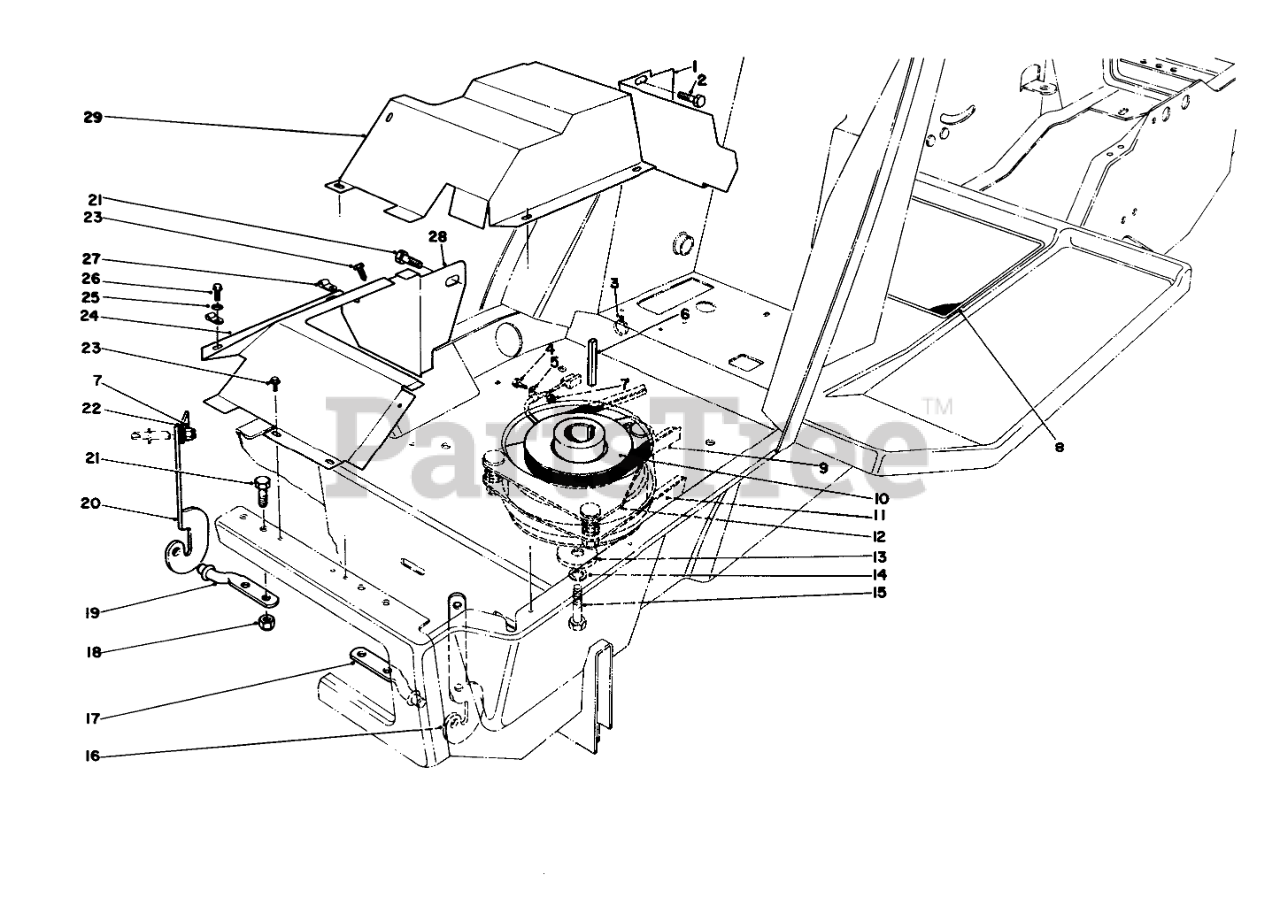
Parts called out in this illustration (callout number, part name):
1	EXH SHIELD SUPT B
2	SCREW-HH
3	TIE-MOUNT, PUSH
4	SCREW-HH
5	CLAMP
6	KEY-SQUARE
7	NUT-LOCK, NI
8	OPERATION DECAL
9	V BELT
10	Pulley
11	V-BELT
12	Clutch Assembly-Deck
13	WASHER-CLUTCH
14	WASHER-LOCK
15	SCREW-HH
16	L.H. HINGE BRACKET
17	LH HOOD HINGE PIN
18	NUT-LOCK, CONE
19	RH HOOD HINGE PIN
20	RH HINGE BRKT
21	SCREW-HH
22	SCREEN SUPT BRKT
23	SCREW-HWHTF
24	Heat Shield
25	WASHER-FLAT
26	SCREW
27	CABLE CLAMP
28	Support Heat Shield
29	HEAT SHIELD WA B
